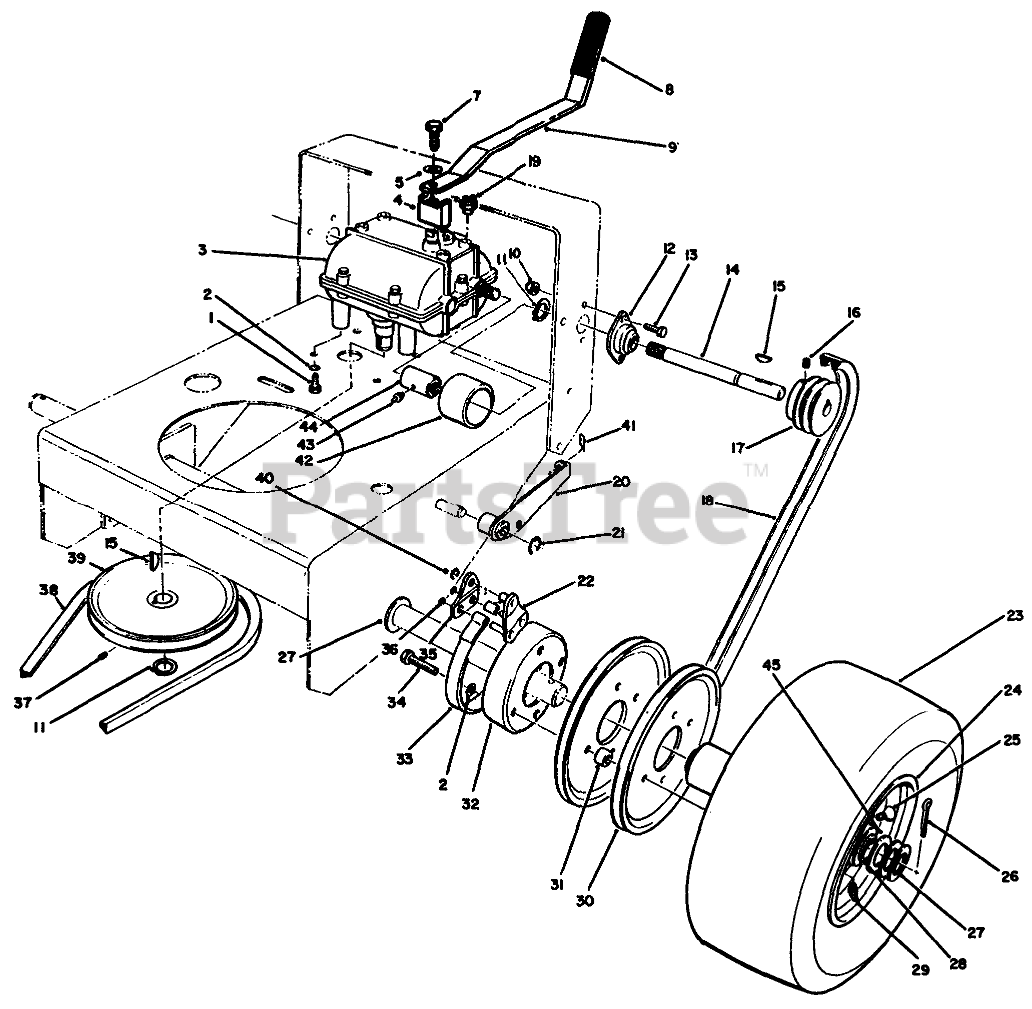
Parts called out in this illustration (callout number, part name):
1	SCREW-HH
2	WASHER-LOCK
3	Transmission
4	MOUNT-LEVER, SHIFT
5	SPACER
7	SCREW-HH
9	SHIFT LEVER R
10	NUT-LOCK, NI
11	RING-SNAP, EXTERNAL
12	BEARING-EXTERNAL SHAFT
13	SCREW-HH
14	SHAFT-EXTENSION, LH
15	KEY-WOODRUFF
16	SCREW-SET, HSH
17	Pulley-Drive
18	V-BELT
19	NEUTRAL SWITCH
20	Brake Arm-LH
21	RING-RETAINING
22	LINK-BRAKE
24	WHEEL AND HUB ASM
25	STEM-VALVE
26	PIN-COTTER
27	WASHER-WHEEL
28	BEARING-BALL, FLANGED
29	FITTING-LUBE, 45 DEG
30	Pulley-Wheel
31	SPACER-PULLEY
32	Drum-Brake
33	BAND-BRAKE
34	SCREW-HH
35	Plate-Link
36	RING-RETAINING
37	SCREW-SET
38	V-BELT
39	PULLEY-DRIVEN
40	RING-RETAINING, EXTERNAL
41	PIN-COTTER
42	GUARD-COUPLER
43	FITTING-GREASE
44	COUPLER
45	WASHER-THRUST
